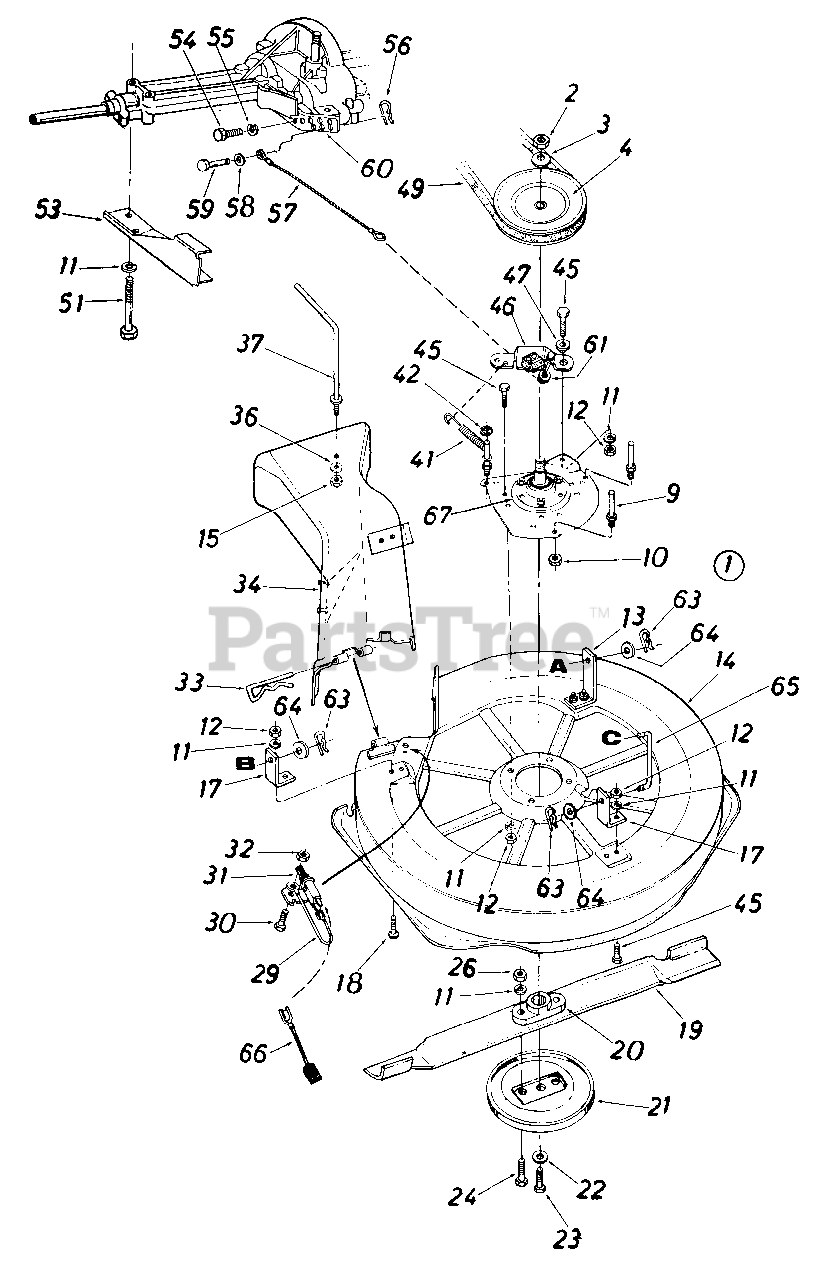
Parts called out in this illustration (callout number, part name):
1	30" R.D. Deck Ass'y. Comp.
2	Hex Jam Nut 5/8-18 Thd.
3	Bell-Wash. .630" I.D. x 1.25"
4	5/8 V-Pulley .75" I.D. x .7"
9	Stud 3/8-16 x 2.75" Lg.
10	Hex Jam Nut 3/8-16 Thd.
11	L-Wash. 5/16" I.D.
12	Hex Nut 5/16-18 Thd.
19	30" High Lift Blade
20	Blade Adapter
21	Scalp Plate
22	L-Wash. 3/8" I.D.
23	Hex Bolt 3/8-24 x 1.0
24	Hex Bolt 5/16-24 x 1.0" Lg.
26	Hex Nut 5/16-24 Thd.
29	Electrical Wire
30	Hex Bolt 1/4-20 x .50" Lg.
31	Safety Switch
32	Hex Nut 1/4-20 Thd.
33	Internal Cotter Pin
34	R.D. Chute Deflector
36	L-Wash. .32" I.D. x .62" O.D.
37	90ø Rod 5/16-18 Thd.
41	Extension Spring
42	Push Speed Nut
45	Hex Bolt 5/16-18 x 75"
46	Blade Brake Brkt. Ass'y.
47	Shoulder Spacer .500" Dia.
49	"V"-Belt 1/2" x 52" Lg.
51	Hex Bolt 5/16-18 x 2 75"
55	L-Wash. 1/4" I.D.
56	Int. Cot. Pin 5/16" Dia.
57	Brake Cable 11.75" Lg.
58	Fl-Wash. .281" I.D. x 50"
59	Clevis Pin 1/4" Dia.
60	Lower Inside Belt Guard
61	Cap Speed Nut 1/4" Rod
63	Int. Cotter Pin 1/2" Dia.
64	Fl-Wash. .531" I.D. x .930"
65	Deck Link 3.9" Lg.
66	Wire Lead
67	Blade Spindle Ass'y. Comp.
